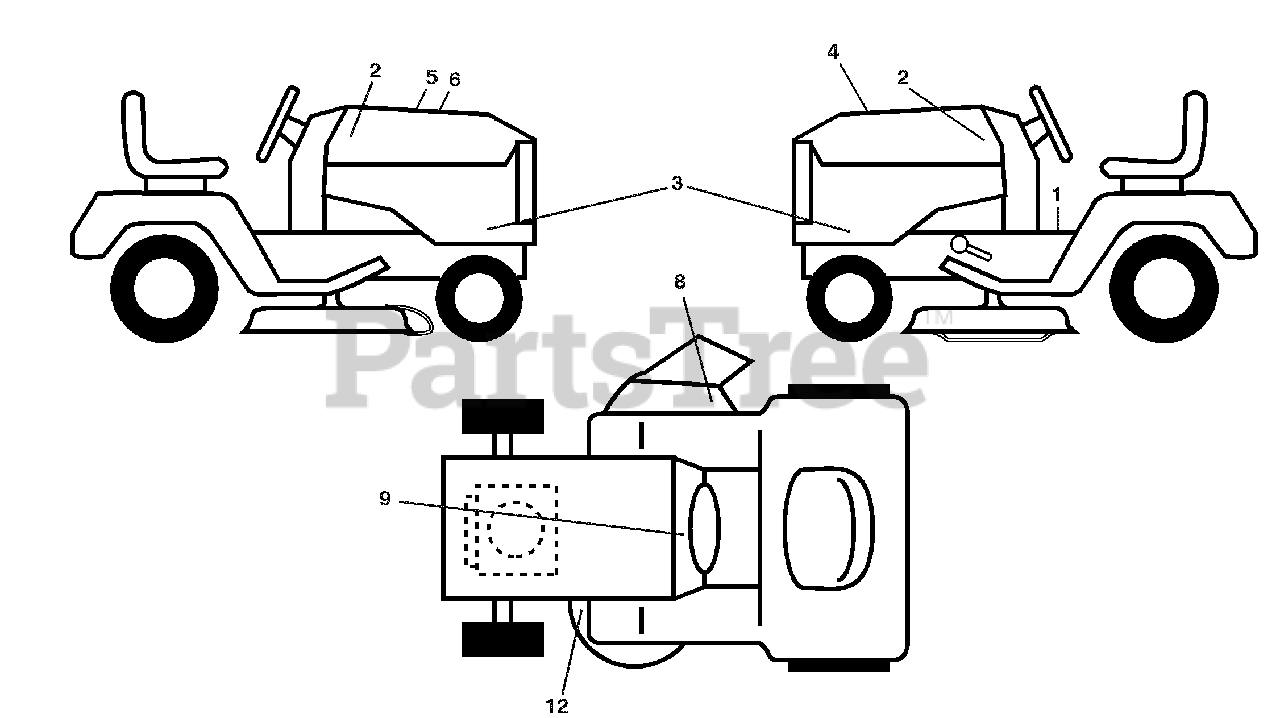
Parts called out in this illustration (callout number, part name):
1	Decal, Operators
2	Decal, Hood
3	Decal, Emblem Panel SD
4	Decal, Engine
5	Decal, Customer Respons.
6	Decal, Replacement
8	Decal Mower Warn Keep Hand away
9	Decal, Battery Dnge/Poi
12	Decal, Mower V-Belt Schematic
